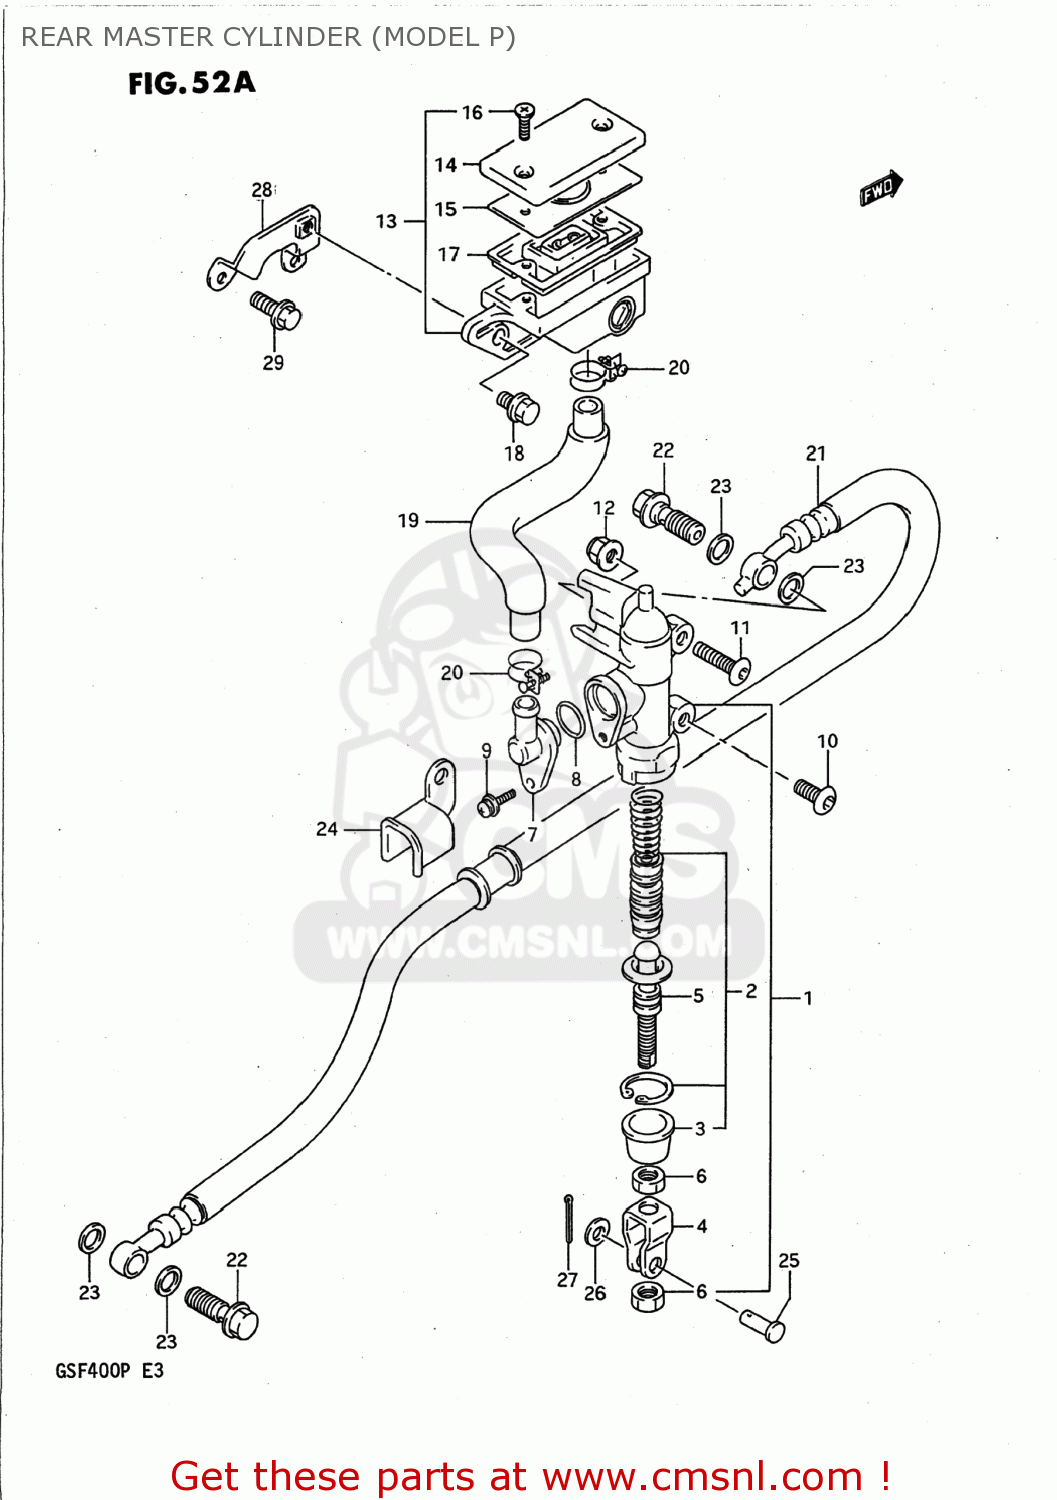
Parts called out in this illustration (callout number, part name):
1	CYLINDER ASSY,RR MASTER
2	PISTON/CUP SET
3	BOOT
4	YOKE
5	ROD,PUSH
6	NUT
7	CONNECTOR
8	O RING
9	SCREW
10	SCREW(6X16)
11	SCREW(6X30)
12	NUT
13	TANK ASSY,RR RESERVOIR
14	CAP
15	PLATE,DIAPHRAGM
16	SCREW
17	18
18	BOLT 6X12
19	HOSE,RESERVOIR TANK
20	CLAMP
21	HOSE,RR BRAKE
22	BOLT UNION
23	WASHER(10X15X1.5)
24	GUIDE,BRAKE HOSE
25	PIN
26	WASHER
27	PIN
28	PLATE,REAR RESERVOIR TANK
29	BOLT
